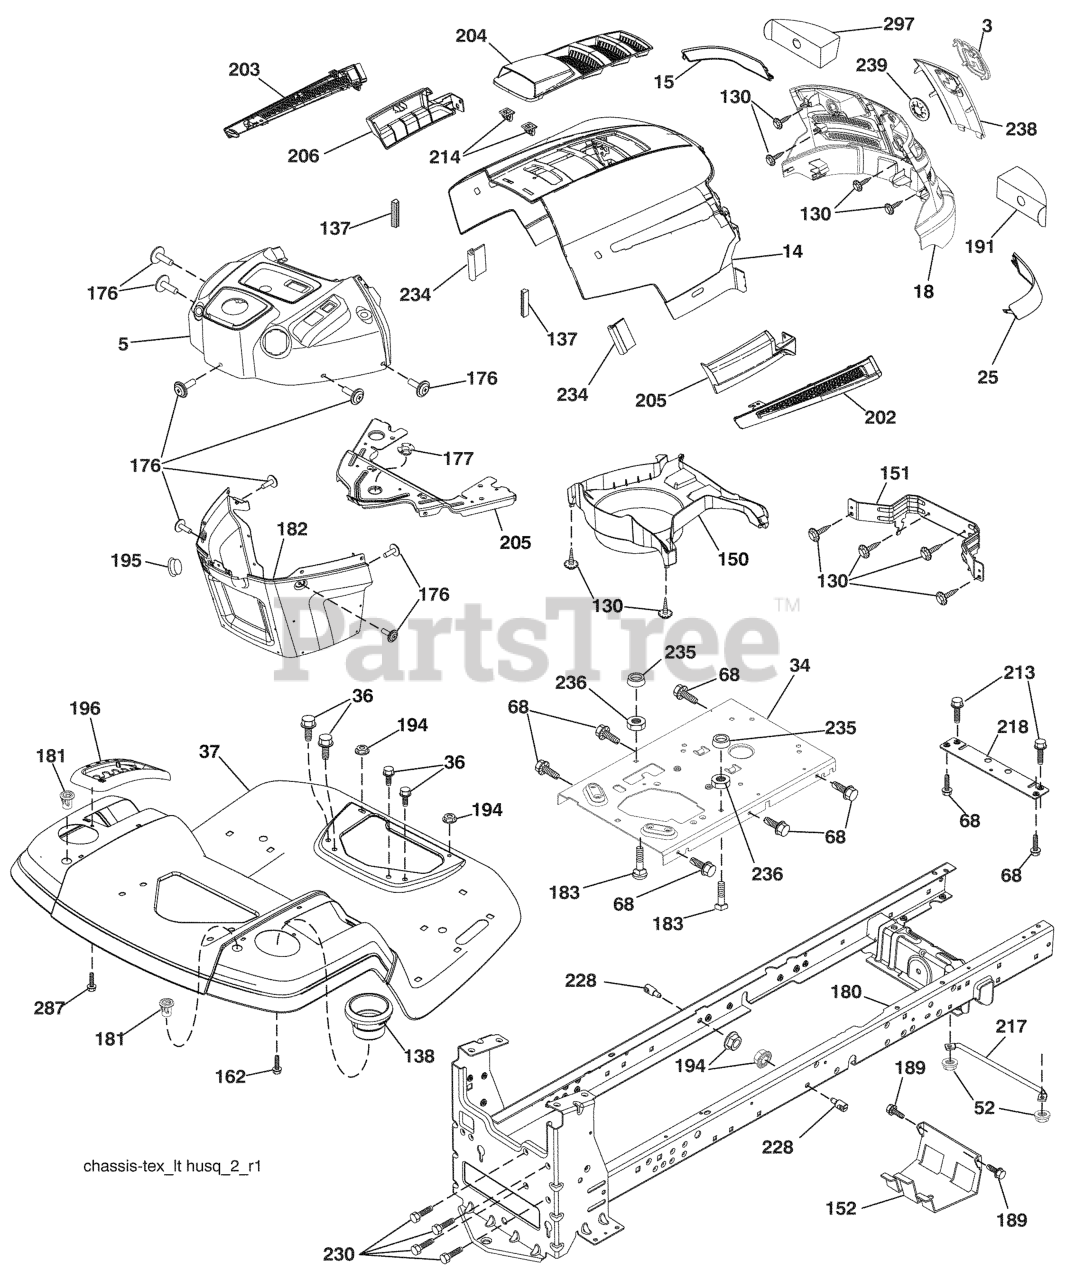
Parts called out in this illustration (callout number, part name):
3	RP LOGO
5	DASH
14	HOOD
15	LENS.HUSQVARNA LT.LH
18	RP GRILLE/LENS ASM.
25	LENS.HUSQVARNA LT.RH
34	PLATE.ENGINE.WELDED.CHASSIS
36	SCREW 5/16"
37	RP FENDER.TLT.FS.W/CPH.422
52	LOCKNUT
68	Screw THDROL 5/16-18 x 1/2
130	SCREW.#10 X 0.750.BOS
137	BUMPER DASH
138	CUPHOLDER.TL.TEX.418
151	BRACKET PIVOT
152	SHIELD.BROWNING.W/TEX
159	SCREW, 3/8-16X3/4
162	SCREW.HI-LO.CONSOLE
175	CROSSMEMBER
176	SCREW.#10-24X5/8.RN.QU
177	BUSHING STEERING
180	CHASSIS
181	BUSHING.MNT.FEND.CRGO.
182	DASH.LOWER.PREDATOR LT
183	BOLT.5/16-18X1-1/4 FULL.THREAD
189	SCREW
191	INSERT REFLECTIVE
194	NUT LOCK HEX FLANGE 5/16-18
195	PLUG DASH
196	RP CONSOLE.ASM.DECKLFT.GR/RBT.
202	VENT SIDE HOOD RH
203	VENT SIDE HOOD LH
204	VENT TOP HOOD
205	SKIRT SIDE RH
206	SKIRT SIDE LH
213	BOLT
214	CLIP.RETAINER.TINNER.
217	ROD.PIVOT.HOOD
218	X-PIECE.HOOD.STOP.NON/
228	STUD.FASTNER.W/ANTI-ROTATE
230	SHOULDER BOLT 5/16-18TT
234	BUMPER.HOOD.TEX.HUSQVARNA
235	SPACER FENDER
236	NUT.CENTERLOCK.5/16-
238	TRIM
287	SCREW 1/4X20
297	INSERT.REFLECTIVE.RH.
